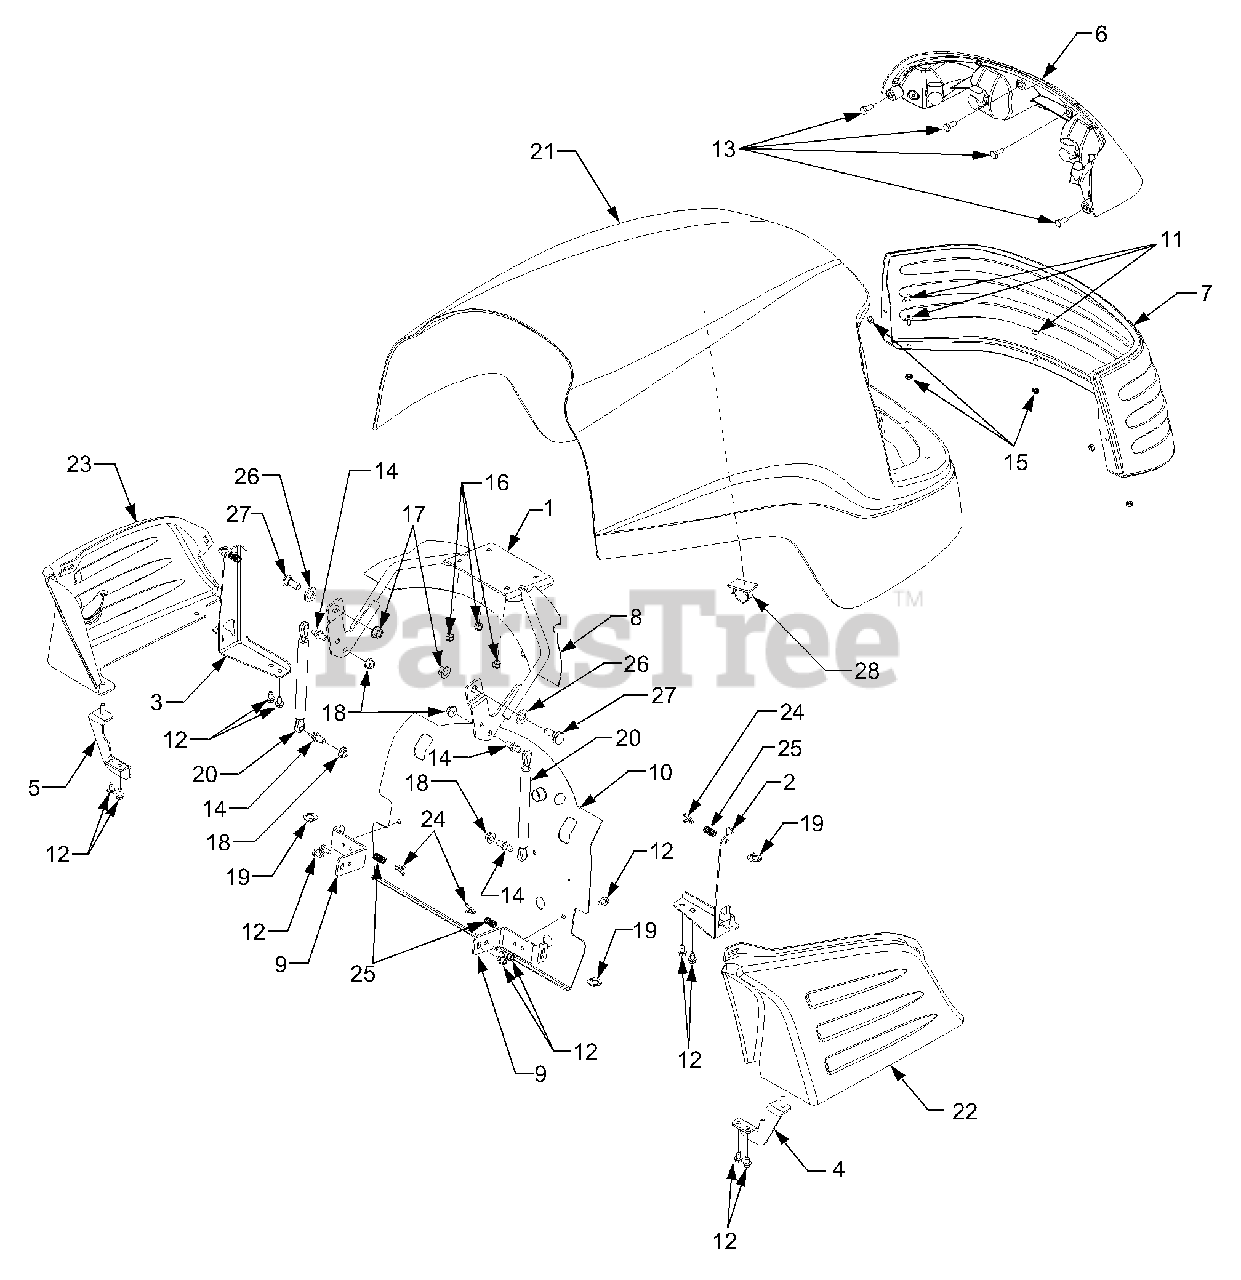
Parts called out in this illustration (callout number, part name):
1	Hinge Assembly, Hood
2	Bracket, Side Panel Mtg. RH
3	Bracket, Side Panel Mtg. LH
4	Bracket, Side Panel Mtg. RH Rear
5	Bracket, Side Panel Mtg. LH Rear
6	Headlight Assembly
9	Bracket, Panel Mtg.
10	Shield, Lower Heat
11	Screw, Truss Hd, 10-24 x .5
12	Screw, Hex Wash Hd Tapp 1/4-20 x .5
13	Screw, Hex Cap, 1/4-20 x .62 GR5
14	Stud, Cylinder, 5/16-18 Thrd
15	Nut, Hex Sems, 10-24
16	Nut, Hex Nylon Insert Lock, 1/4-20
17	Nut, Hex Flange Lock, 3/8-16
18	Nut, Hex Flange Lock, 5/16-18
19	Latch, 1/4 Turn Panel
20	Cylinder, Gas Spring
21	Hood, Service Kit
21	Hood
22	Panel, Side RH
23	Panel, Side LH
24	Clip, Spring
25	Spring, Compression
26	Washer, Flat, .510 x .1.0 x .060
27	Screw, Shoulder, .5 x .27 Lg 3/8-16
28	Clip, Retaining
